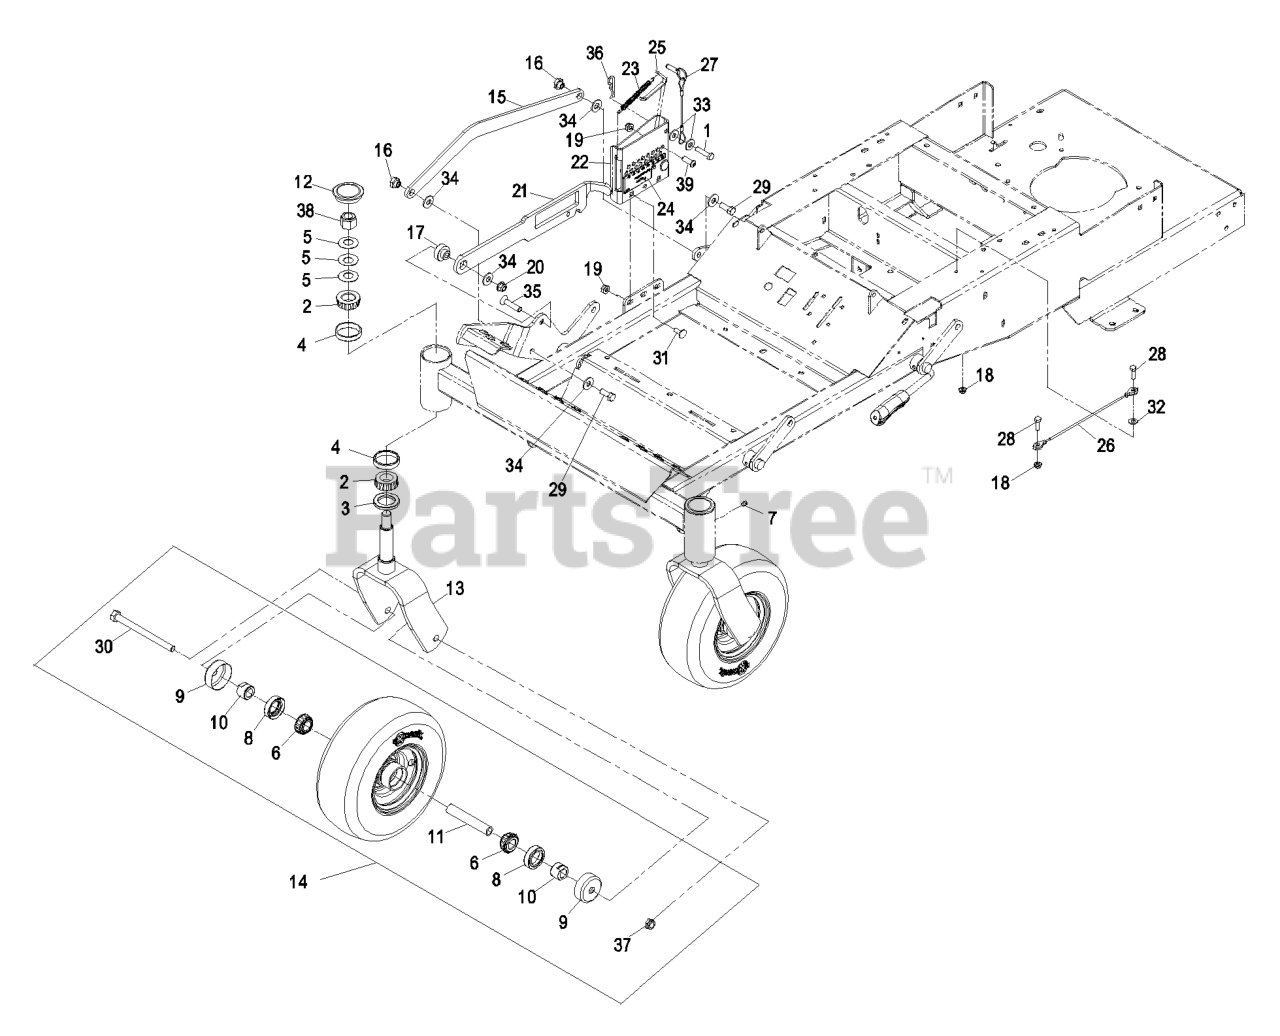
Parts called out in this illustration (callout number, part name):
1	PIN-CLEVIS
2	Cone-Bearing Tapered Roller
3	SEAL-GREASE
4	CUP-BEARING
5	WASHER-BELLVILLE
6	BEARING-CONE, TAPERED ROLLER
8	SEAL-CASTER
9	GUARD-SEAL
10	SPACER-NUT
12	CAP-GREASE
13	FORK-CASTER
14	WHEEL/TIRE AND BEARING AS
15	LINK-CONTROL, DECK
16	NUT-SHOULDER
17	BUSHING
19	NUT-HF, NI
20	NUT-HF, NI
21	PLATE,HEIGHT CONTROL
22	HEIGHT ADJUST ASM
23	SPRING-ADJUST, HEIGHT
24	DECAL-HEIGHT, DECK
25	PAWL-CONTROL, HEIGHT
26	CABLE-STOP, SEAT
27	HEIGHT PIN W/LANYARD ASM
28	SCREW-HH
29	SCREW-HH
30	SCREW-HH
31	SCREW-CARR
32	WASHER-PLAIN
33	WASHER-SPRING
35	SCREW-FH
36	PIN-COTTER
37	NUT-HEX
38	NUT-LOCK, NI
39	SCREW-HSBH
